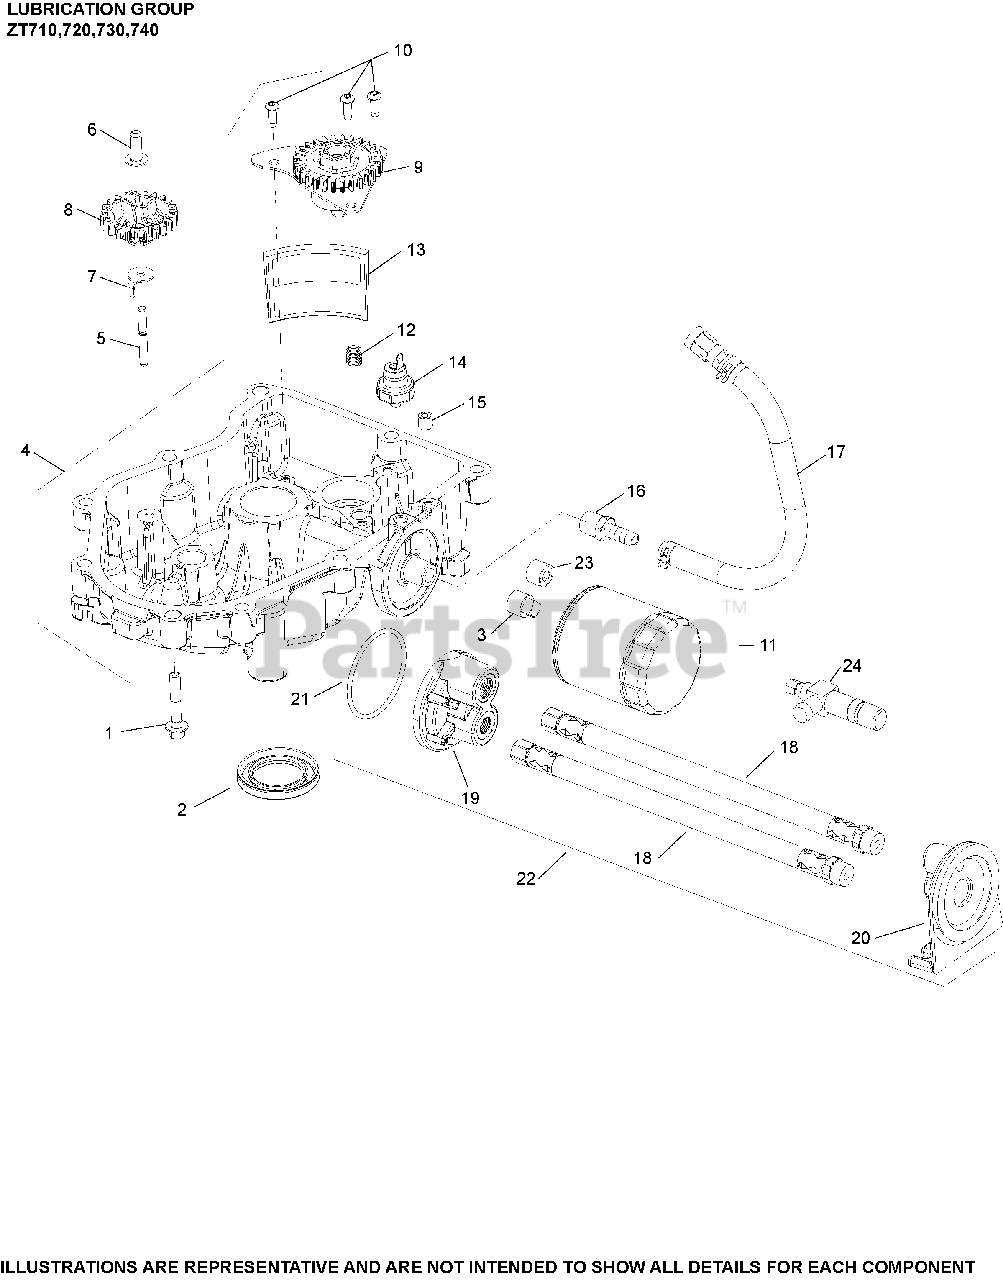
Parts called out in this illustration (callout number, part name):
1	SCREW, FLG M8X1.25X45
2	SEAL, OIL
3	PLUG, SQ HD PIPE 3/8"
4	PAN ASSEMBLY, OIL
5	SHAFT, GOVERNOR GEAR
6	PIN, GOVERNOR REGULATING
7	TAB, LOCKING
8	KIT, GOVERNOR GEAR
9	PUMP ASSEMBLY, OIL
10	SCREW, BUTTON HEAD
11	OIL FILTER
12	SPRING, COMPRESSION
13	SCREEN, OIL
15	PLUG, CTSK PIPE 1/8"
